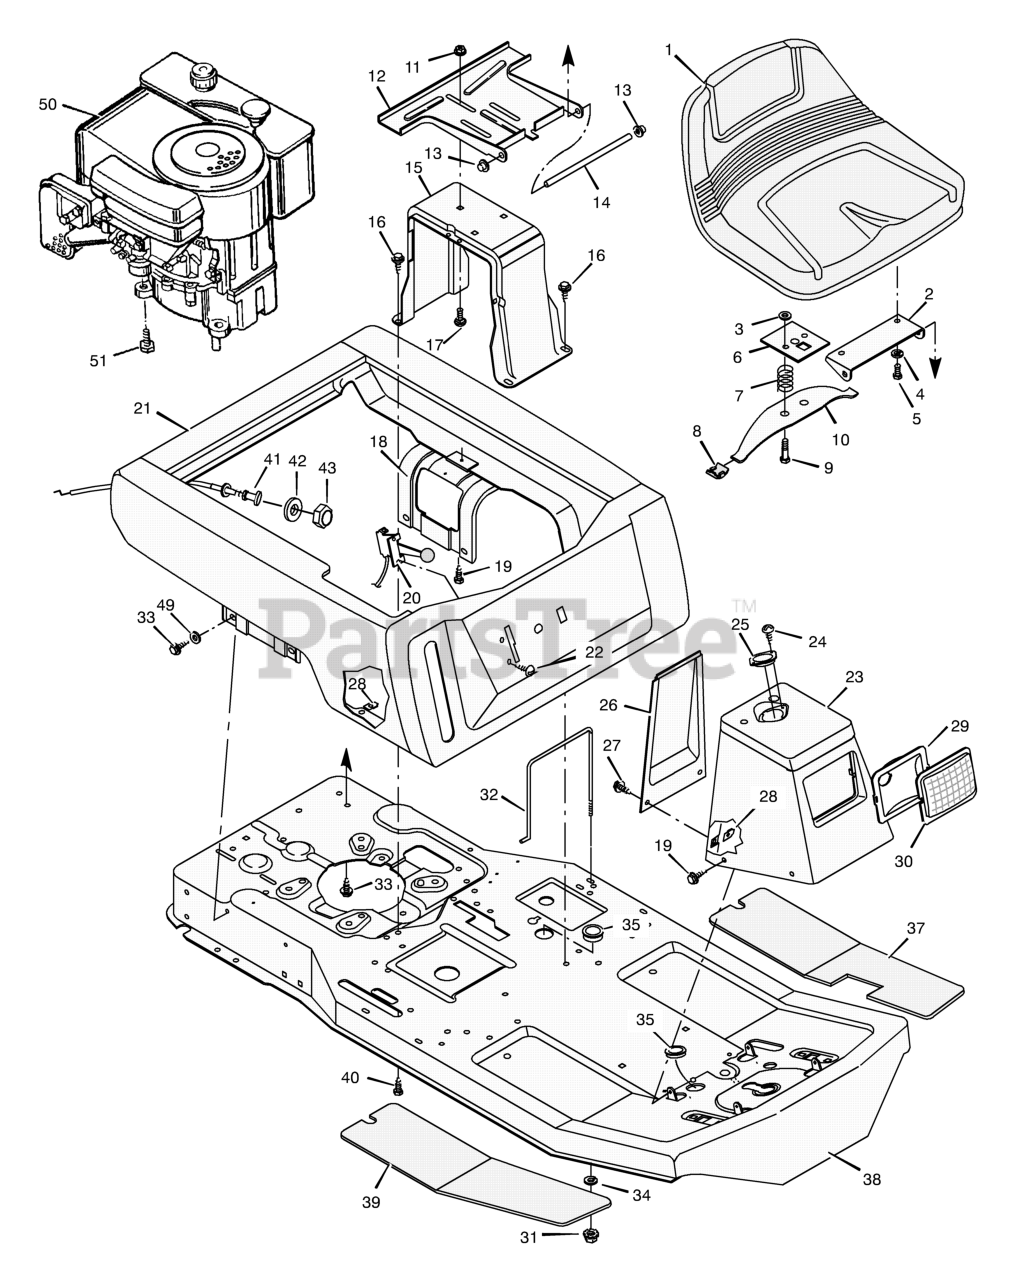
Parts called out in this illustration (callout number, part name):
2	Hinge, Seat
3	Retainer
4	Lockwasher
5	Bolt, Hex
6	Plate, Seat Switch
7	Spring, Compression
8	Glide, Seat Spring
9	Bolt, Shoulder
10	Spring, Seat
11	Locknut, Flange
12	Bracket, Seat Pivot
13	Cap, Push On
14	Rod, Seat Hinge
15	Support, Seat
17	Bolt, Carriage
18	Support, Body
20	Throttle Control
23	Console Assembly
25	Bearing, Steering Post
26	Console, Plate
29	Reflector
31	Locknut
32	Clamp, Battery
34	Washer
35	Grommet
37	Mat, Left
38	Frame Assembly
39	Mat, Right
42	Washer
49	Washer
50	Engine *
51	Bolt, Engine Mount
